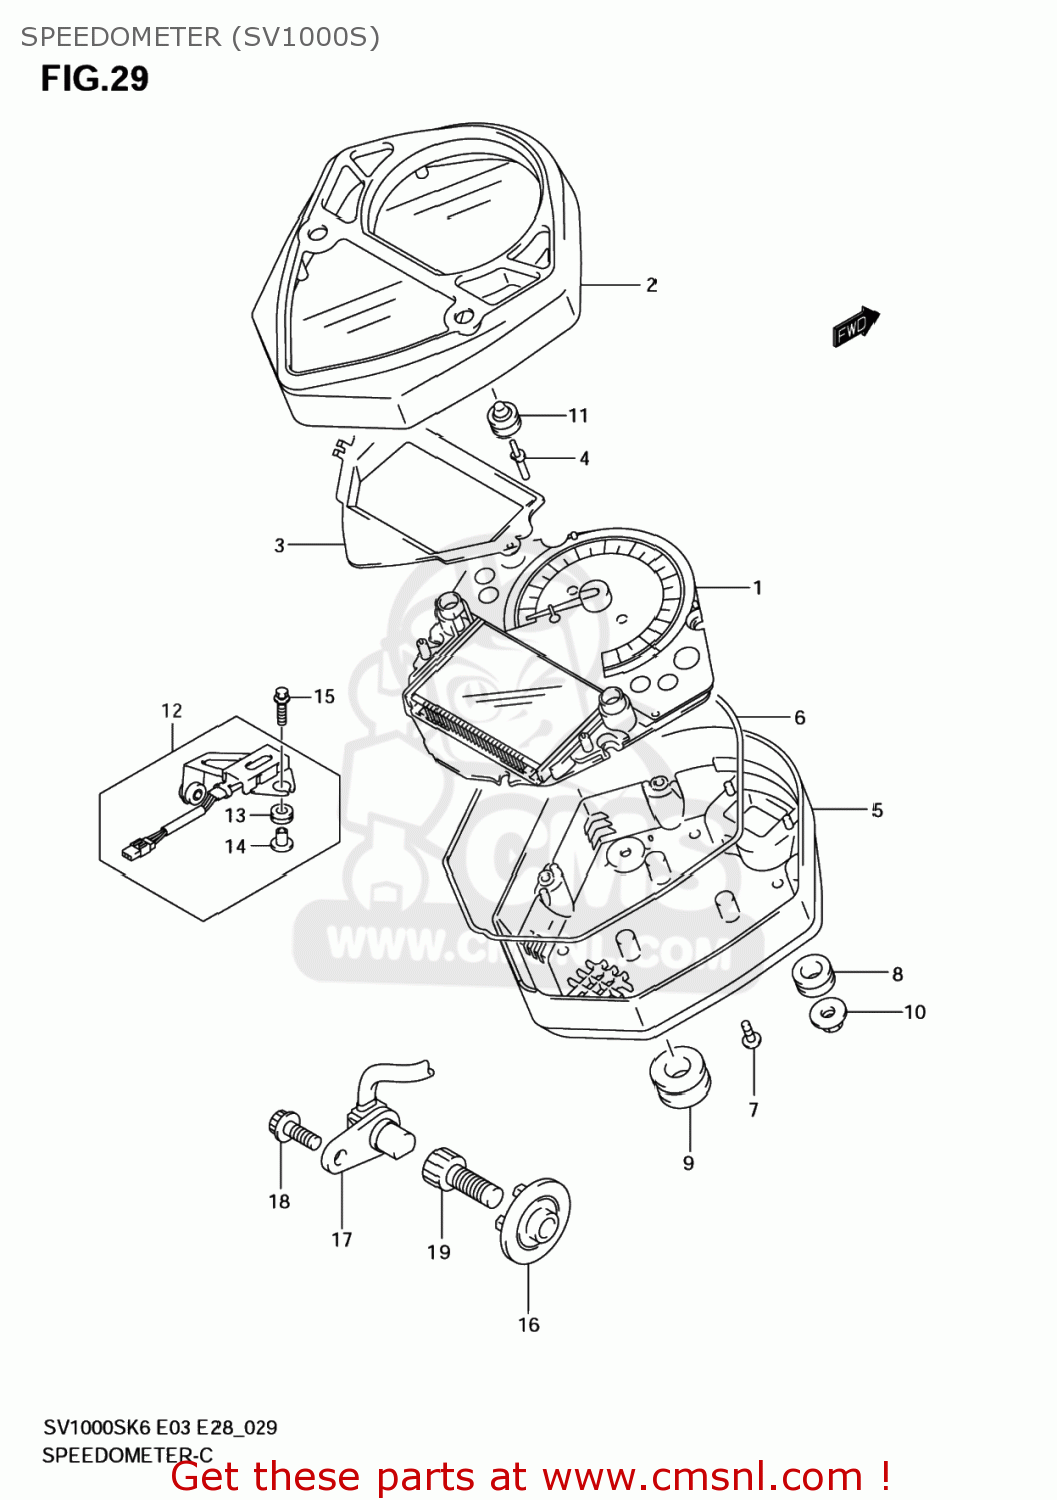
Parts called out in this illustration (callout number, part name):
1	SPEEDOMETER
2	CASE,SPEEDOMETER UPR
3	PLATE,SPEEDOMETER
4	KNOB,SPEEDOMETER
5	CASE,SPEEDOMETER LWR
6	GASKET,METER CASE (NAS)
7	CUSHION
8	CUSHION
9	NUT
10	SCREW,SPEEDOMETER
11	COVER,SPEEDOMETER KNOB
12	RESISTOR ASSY
13	CUSHION
14	SPACER(6.5X10X11.6)
15	BOLT(6X25)
16	ROTOR,SPEED
17	SENSOR,SPEED
18	BOLT
19	BOLT
